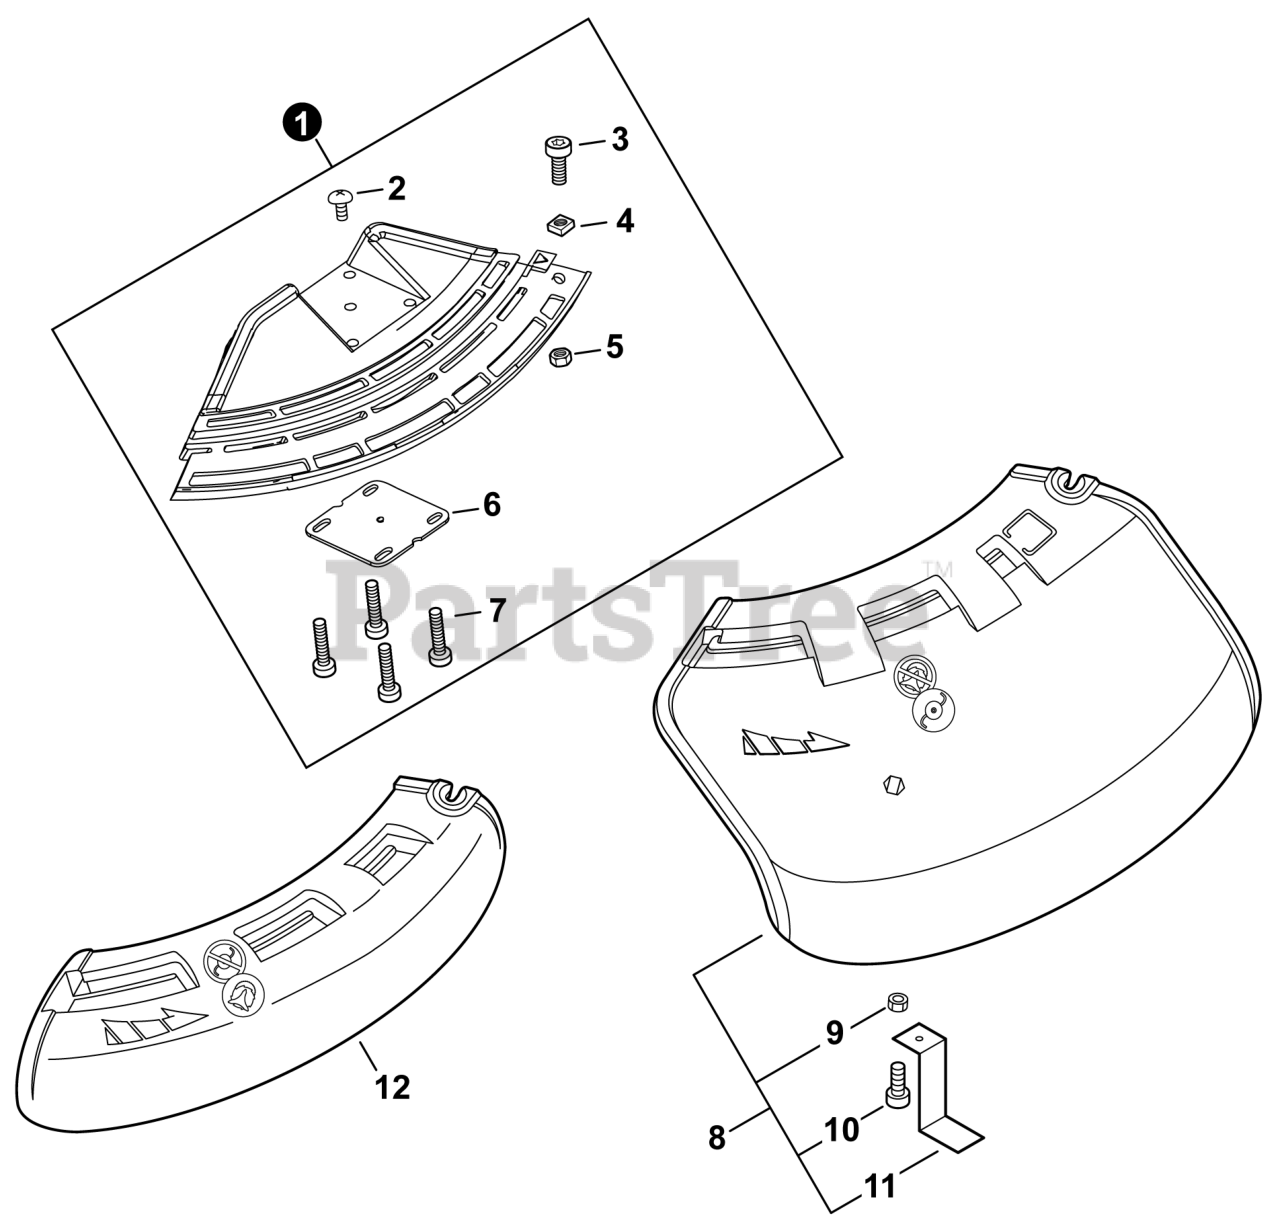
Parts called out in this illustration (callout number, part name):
1	DEBRIS SHIELD BASE ASSY
3	BOLT, TORX 5×25
4	NUT M5
5	NUT, LOCK M5
6	PLATE, SHIELD
7	BOLT, TORX 5×25
8	DEBRIS SHIELD ASSY - TRIMMER EXTENSION
10	BOLT, TORX 5×16
12	SHIELD, BLADE
